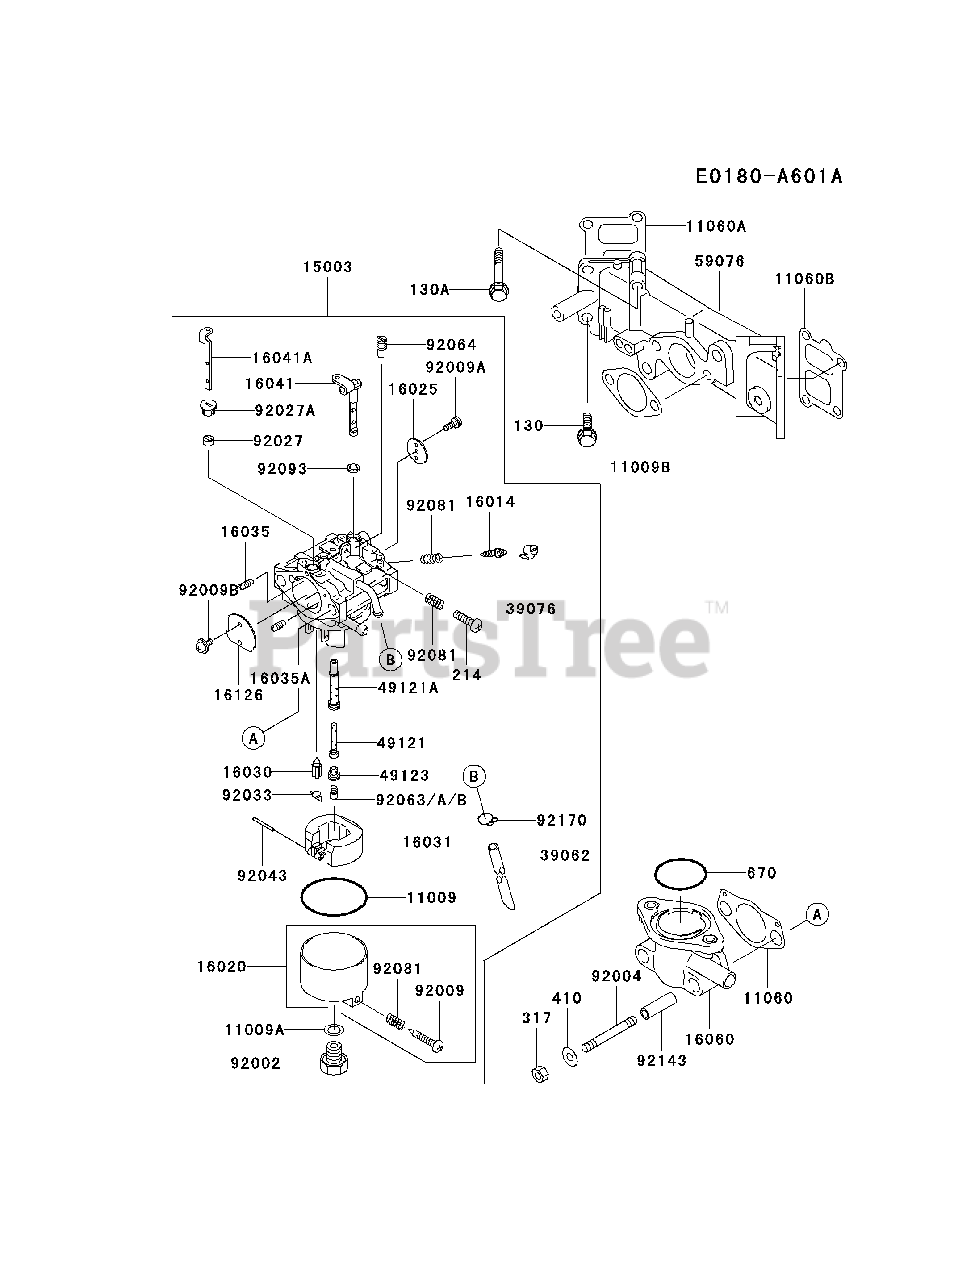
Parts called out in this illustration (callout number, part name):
130	BOLT-FLANGED,6X20
130A	BOLT-FLANGED,6X45
214	SCREW-PAN+-,4X14
317	NUT-HEX-SMALL,8MM
410	W-PLAIN-S,8MM
670	O RING,36MM
